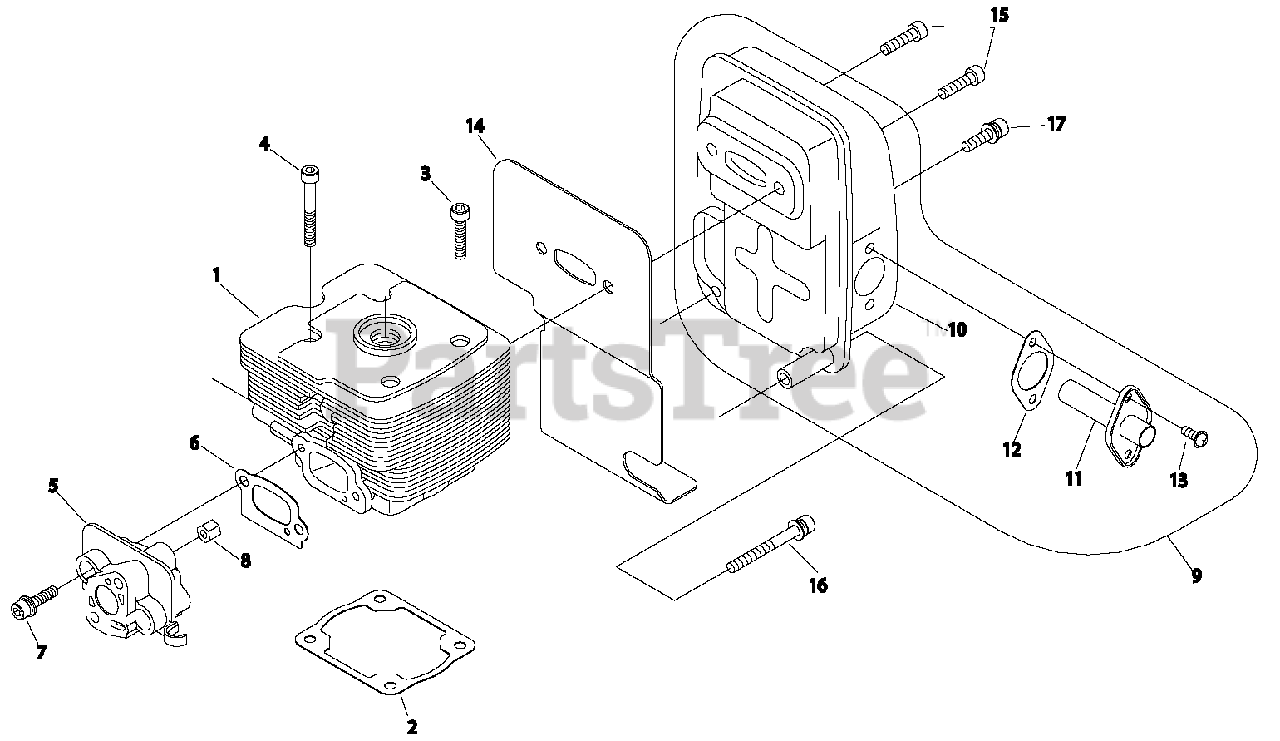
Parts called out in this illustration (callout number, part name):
1	CYLINDER
2	GASKET, CYLINDER
3	BOLT 5×25
4	SCREW - 5×35
5	INSULATOR, INTAKE
6	GASKET, INTAKE
7	BOLT M5×30
8	NUT
9	MUFFLER ASSY
10	MUFFLER
11	PIPE, EXHAUST
12	GASKET, EXHAUST
13	SCREW M4×12
14	HEAT SHIELD, EXHAUST
15	BOLT 6×25
16	BOLT M5×45
17	BOLT M5×16
